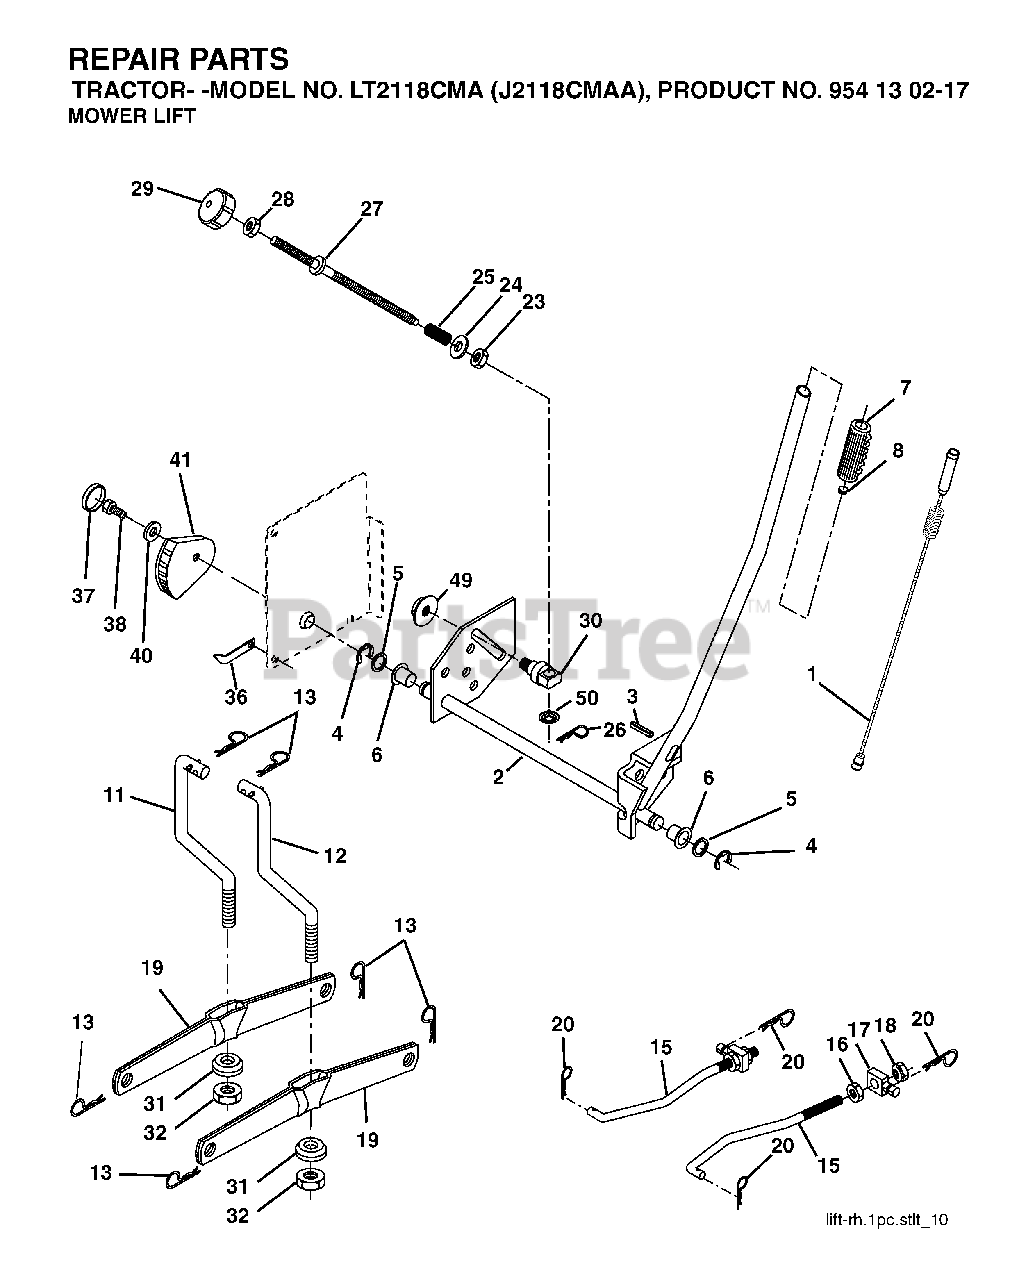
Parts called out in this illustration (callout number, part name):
1	WIRE, INNER
3	PIN GROOVE
4	RETAINING RING LT
6	BEARING.NYLON
7	GRIP HANDLE
8	PLUNGER BUT KIT
11	LINK
12	LINK
13	RETAINER-SPRNG RB
15	LINK.SUSPENSION.FRONT
16	NUT
18	NUT
19	ARM.REAR.SUSPENSION
20	SPRING RETAINER
26	RETAINER CLIP
28	NUT
29	KNOB INF 3/8-16
31	BEARING.PIVOT.LIFT
32	NUT CROWNLOCK 3/8-24
36	POINTER, HEIGHT INDICATOR
37	PLUG,HOLE
38	SCREW 5/16-18X1
41	HEIGHT INDICATOR
49	NUT
50	NUT PUSH M
